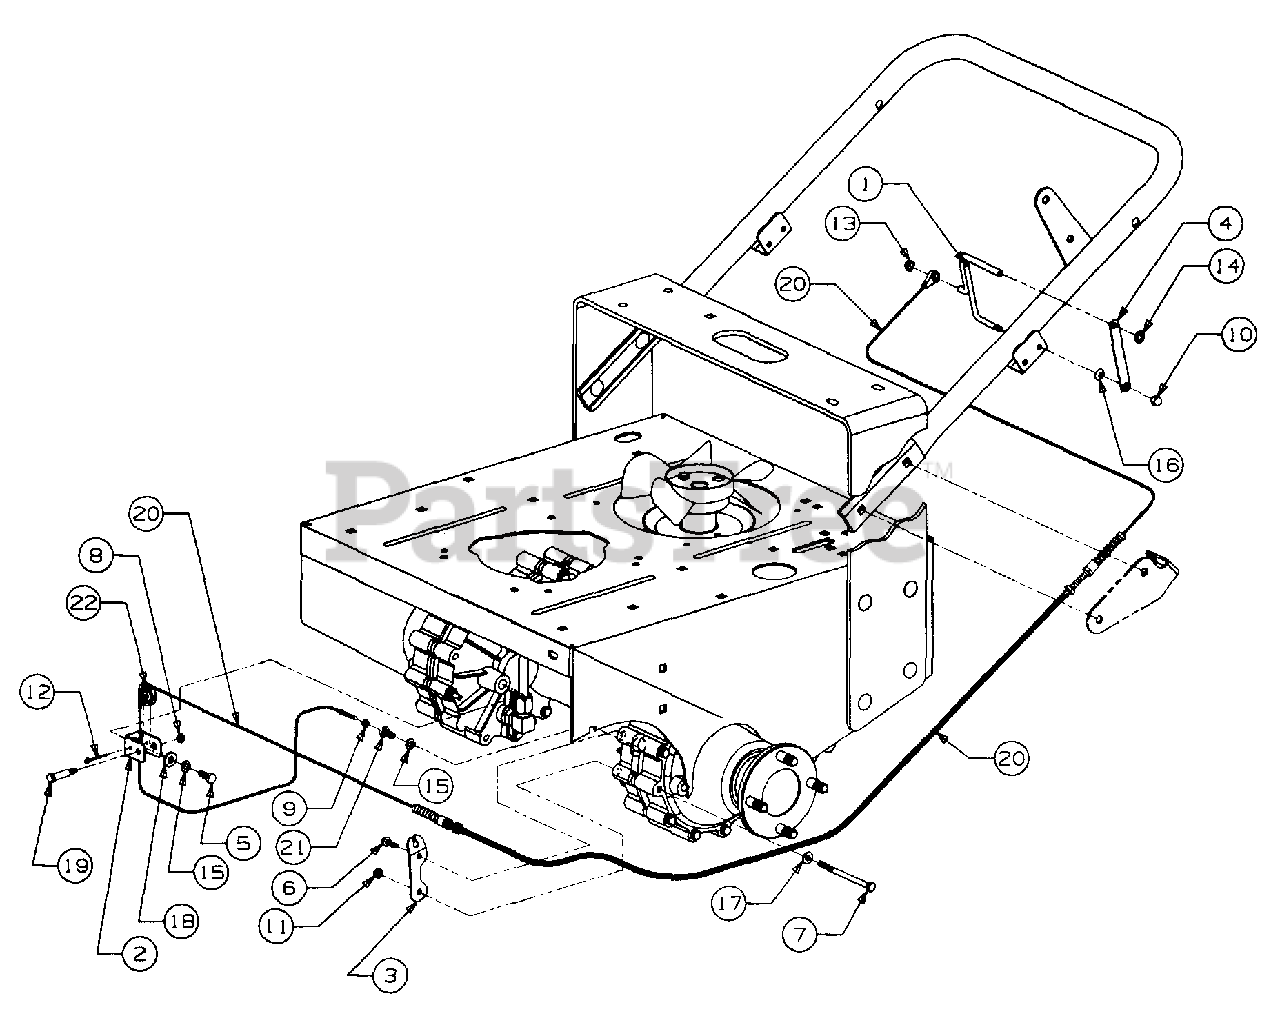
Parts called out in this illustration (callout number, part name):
1	Lever, Drive Wheel Release
2	Bracket, Pulley Mtg
3	Plate, Release Cable Mtg
4	Plate, Retainer
5	Screw, Hex Cap, 5/16-24 X .75 Lg GR5
6	Screw, Hex Wash Hd Tapp, 1/4-20 X .75 Lg
7	Screw, Hex Cap, 1/4-20 X 4.0 Lg
8	Nut, Hex Top Lock, 1/4-20
9	Nut, Hex, #10-32
10	Nut, Hex Lock Stop, 1/4-28
11	Nut, Hex Top Lock, 1/4-20 GR5
12	Pin, Cotter, 5/32 Dia X 1.25 Lg
13	Nut, Cap Speed, .312 Stud
14	Nut, Push-On Speed, 5/16
15	Washer, Lock, 5/16
16	Washer, Spring
17	Washer, Flat, .25 X .62
18	Washer, Flat, .312 X .750 X .119 Thk
19	Bolt, Pulley
20	Cable, Drive Wheel Release
21	Bolt, Cable Adapter
22	Pulley, Cable
